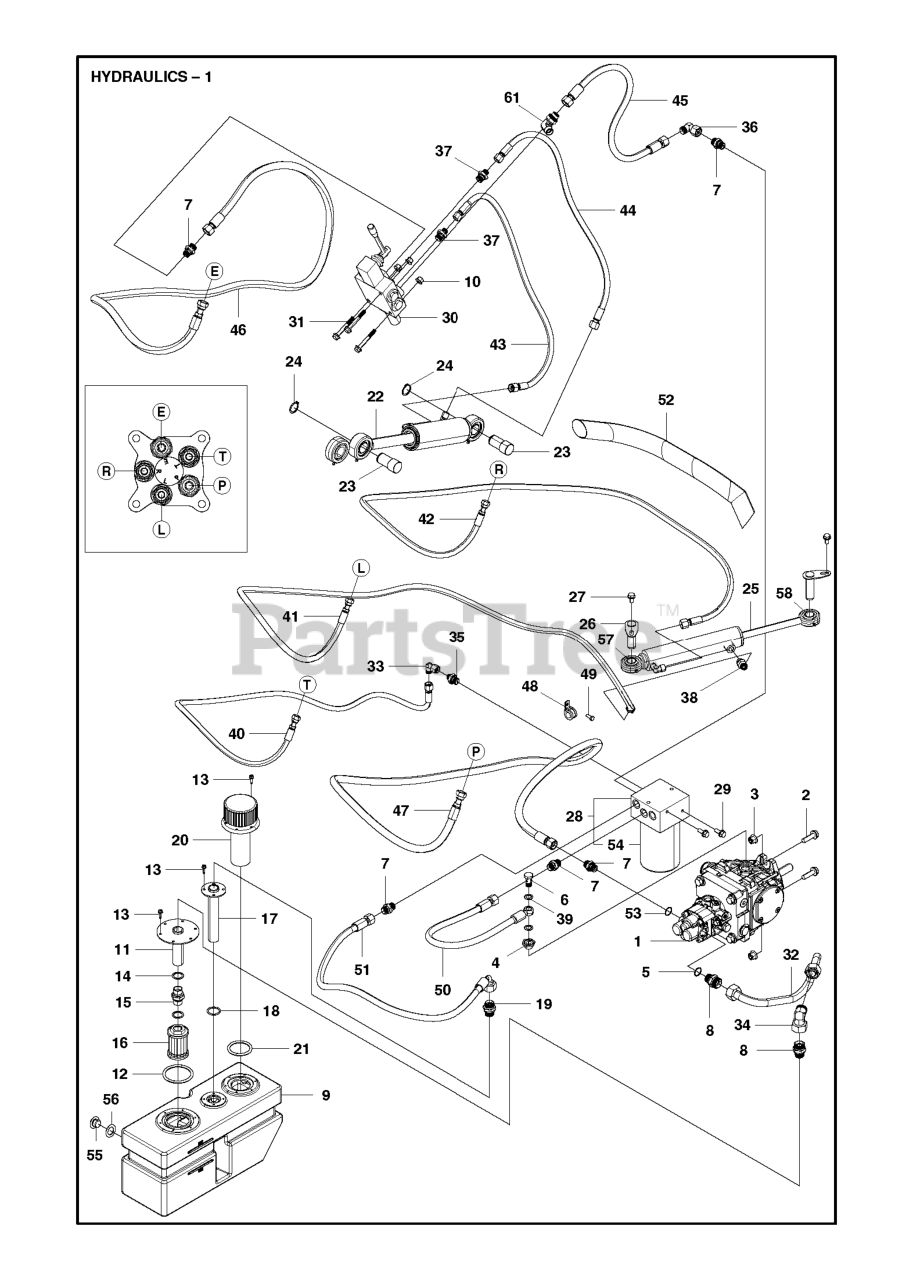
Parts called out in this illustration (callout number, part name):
10	NUT FLANGE
12	O-RING 61.2X5.7 NITRIL
15	PIPE FITTING G STRAIGHT 1/2-1/
16	FILTER PUMP SUCTION, AWD
18	O-RING 26.2X3.0 NITRILE
21	O-RING 47.2X5.7 NITRIL
24	RETAINING RING SGA 25
39	GASKET 20X14X1.5 COPPER
48	HOSE CLAMP
53	REPL BY 740 48 14-02
